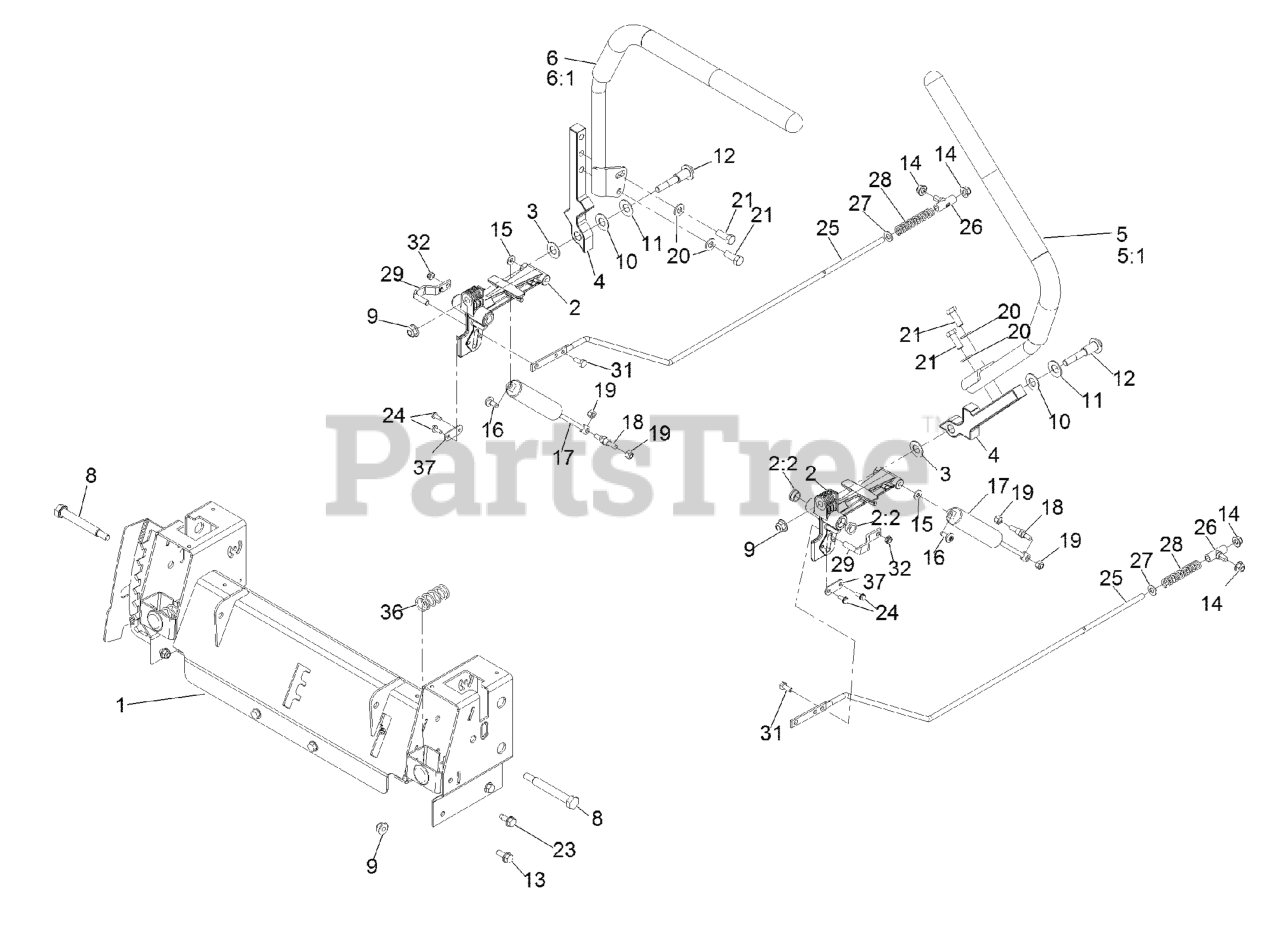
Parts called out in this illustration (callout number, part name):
1	CONTROL-BOX
2	ACTUATOR ARM ASM
2:2	BUSHING-FLANGE
3	WASHER-NYLON
4	ARM-CONTROL
5	HANDLE-CONTROL, LH
6	HANDLE-CONTROL, RH
8	BOLT-PIVOT
9	NUT-HF, NI
11	WASHER-BELLEVILLE
12	BOLT-PIVOT
13	SCREW-HHF
14	NUT-HF, NI
16	SCREW-SHOULDER
18	STUD-DAMPER
19	NUT-LOCK, NI
20	WASHER-FLAT
21	SCREW-HH
23	Screw-HWH 5/16-18 X 3/4 Tf
24	SCREW-TAPTITE
25	Screw-HWH #10-24 X 1/2 Taptite
26	Screw-HWH #10-24 X 1/2 Taptite
26	Rod-Hydro
27	WASHER-PLAIN
28	SPRING-RETURN, NEUTRAL
29	PIN-ROD, HYDRO
31	SCREW-HH
32	NUT-LOCK, NI
36	SPRING-RETURN
37	PLATE-STOP, HYDRO
